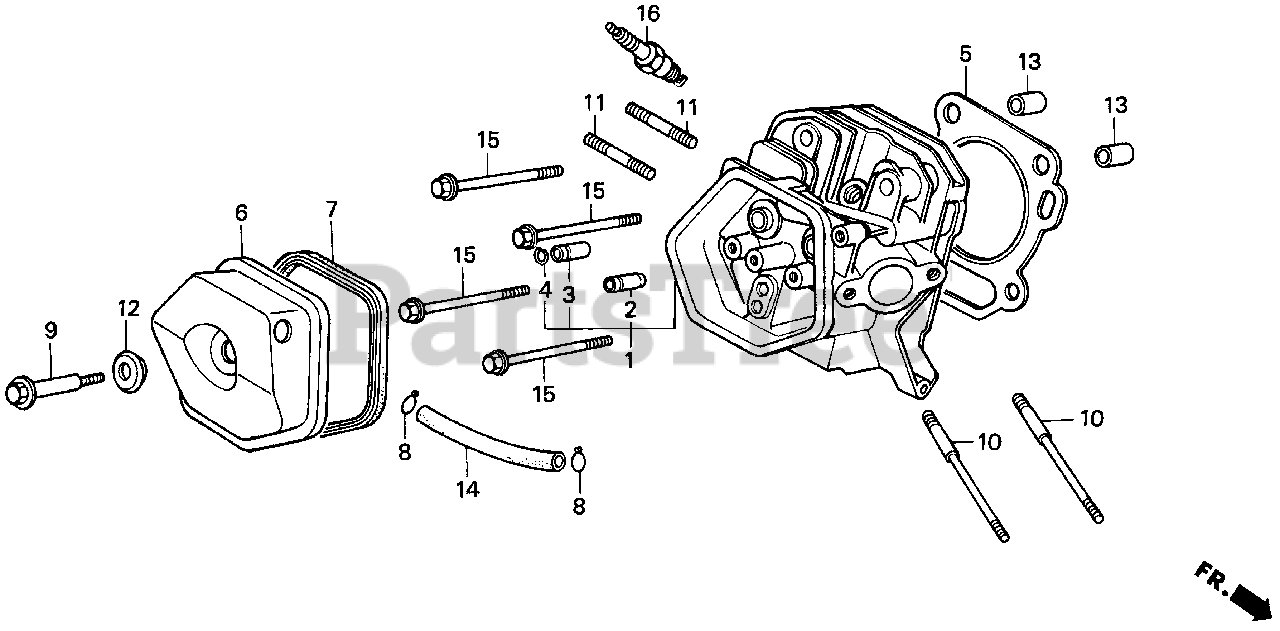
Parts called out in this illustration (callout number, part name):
1	CYLINDER HEAD
2	GUIDE, VALVE (OS)
3	GUIDE, EX. VALVE (OS)
4	CLIP, VALVE GUIDE
5	GASKET, CYLINDER HEAD
6	COVER KIT, HEAD
6	COVER, HEAD
7	GASKET, CYLINDER HEAD COVER
9	BOLT, HEAD COVER
10	BOLT, STUD (8X131.5)
11	BOLT, STUD
11	BOLT 2, STUD (8X32)
12	WASHER, HEAD COVER
13	PIN A, DOWEL (12X20)
14	BULK HOSE, VACUUM (11X1000) (11X105)
15	BOLT, FLANGE (10X80)
16	SPARK PLUG (BPR5ES) (NGK)
16	SPARK PLUG (W16EPR-U) (DENSO)
16	SPARK PLUG (BPR6ES) (NGK)
16	SPARK PLUG (W20EPR-U) (DENSO)
